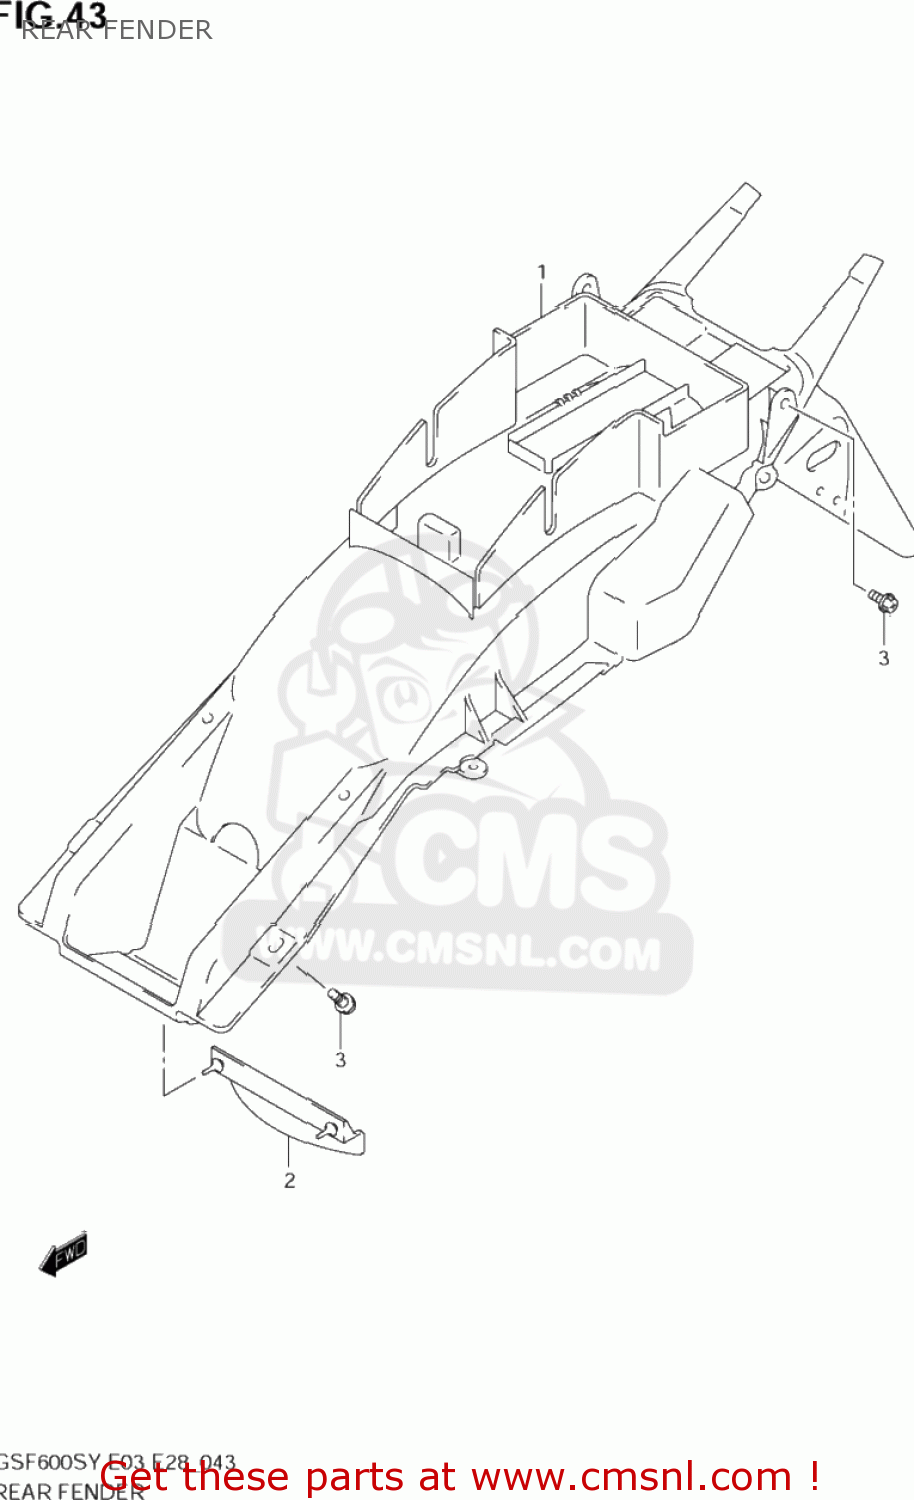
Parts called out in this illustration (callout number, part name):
1	FENDER,RR
2	MUDGUARD,RR FENDER
3	BOLT(6X16)
